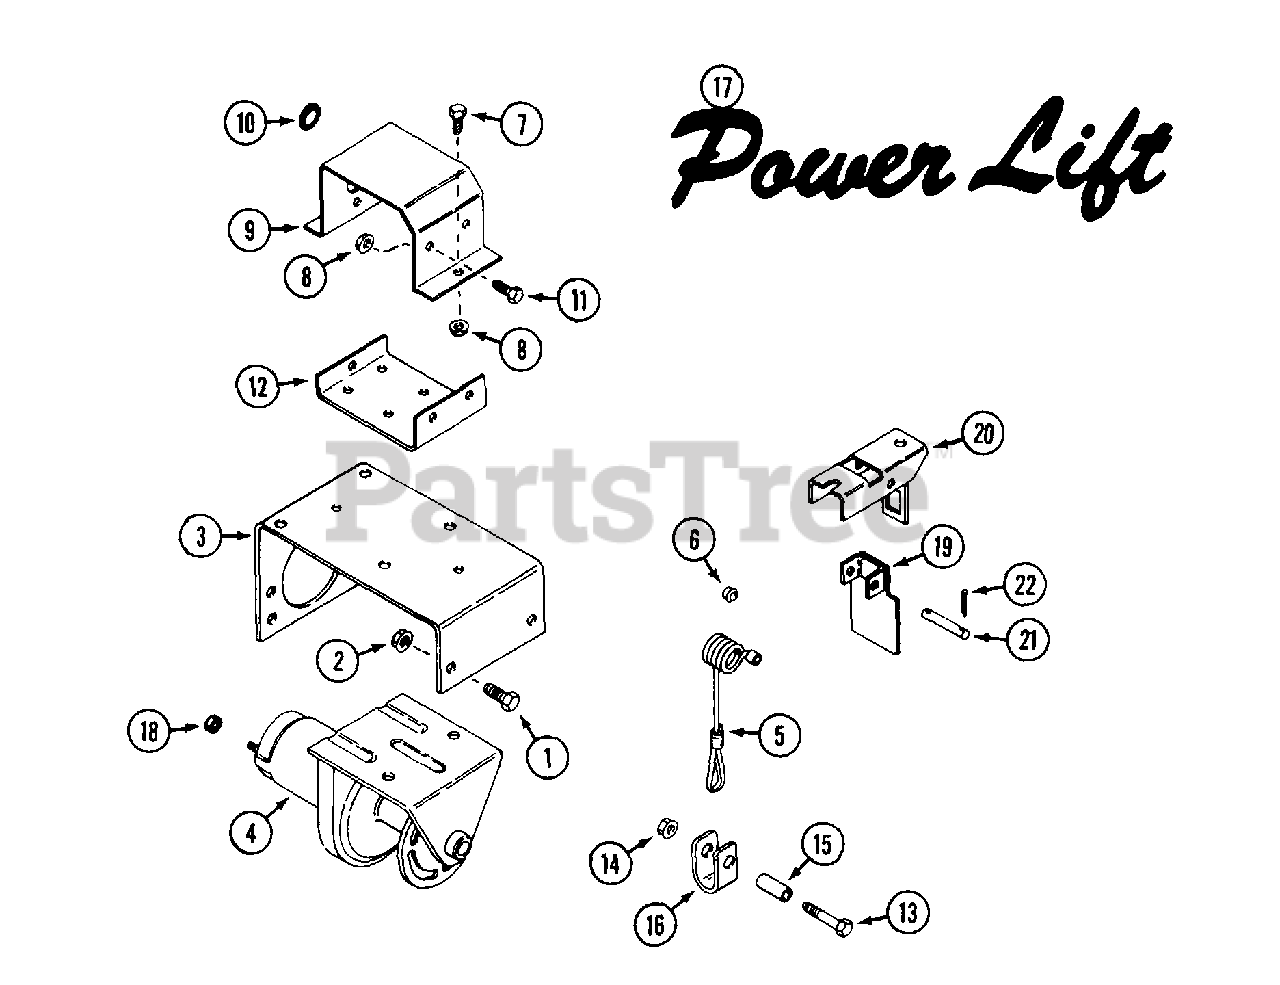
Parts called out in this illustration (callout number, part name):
1	BOLT - 3/8" - 16 x 1"
2	NUT - 3/8" - 16 flange lock
3	MOUNT - winch
4	WINCH - deck lift
6	PIN - cable keeper
7	BOLT - 1/4" - 20 x 3/4"
8	NUT - 1/4" - 20 flange lock
9	COVER - solenoid
10	GROMMET - 1" x 7/8"
11	BOLT - 1/4" - 20 x 1/2"
12	MOUNT - solenoid
13	BOLT - 3/8" - 16 x 2"
14	NUT - 3/8" - 16 lock
17	DECAL - "Power Lift"
18	NUT - #10 - 32
20	MOUNT - trip arm
22	PIN - cotter 1/16" x 5/8"
